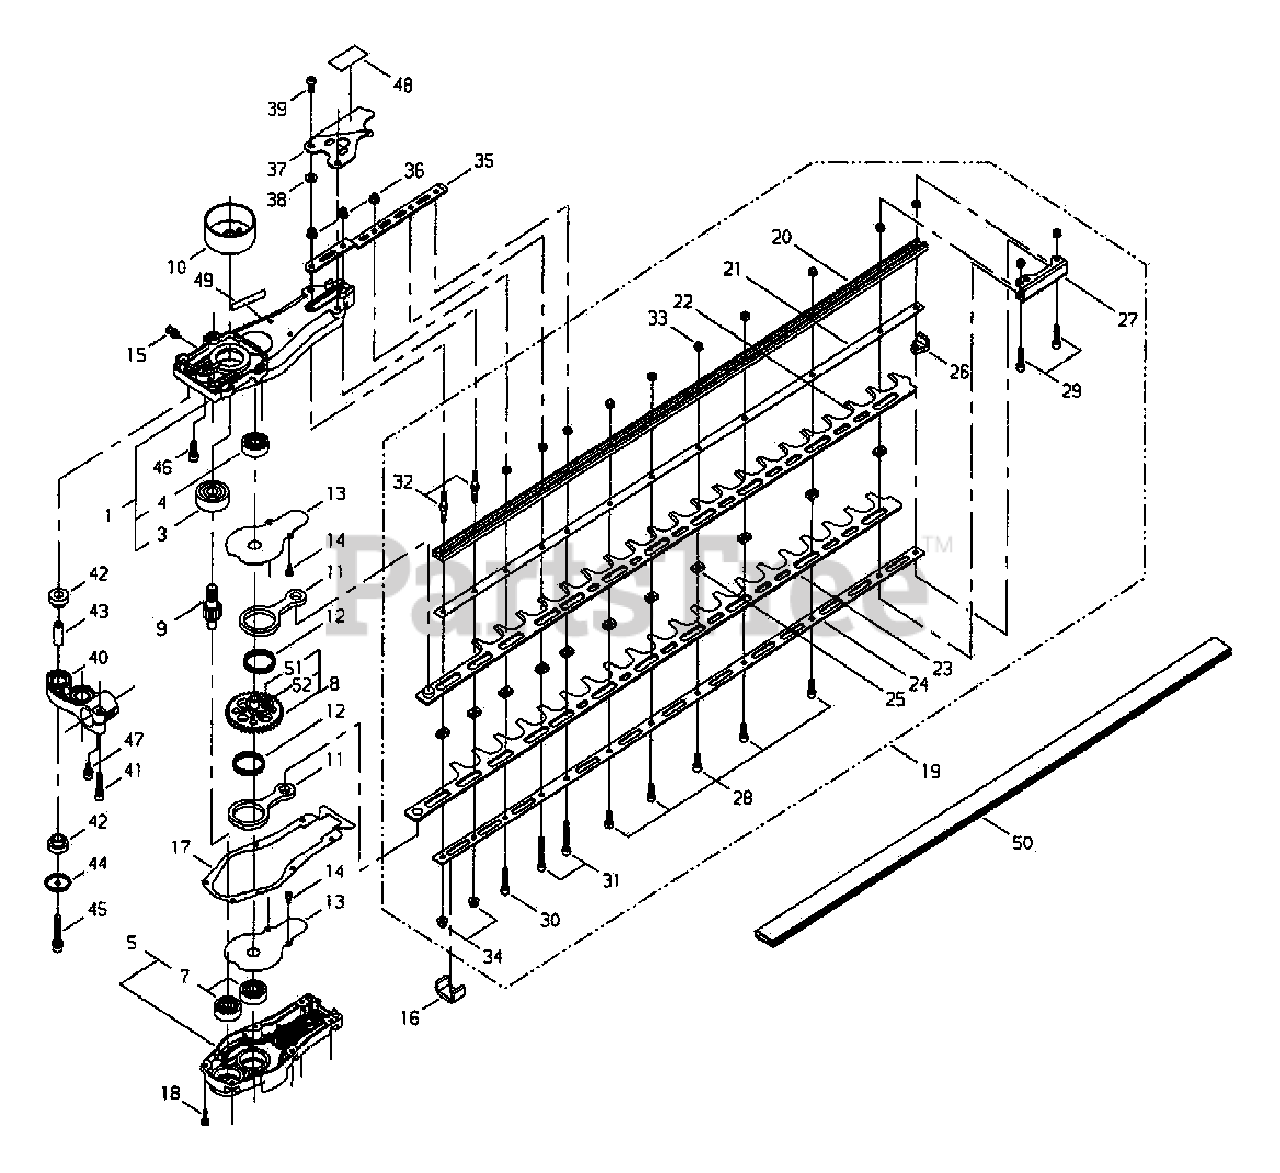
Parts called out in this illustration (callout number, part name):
1	GEAR CASE ASSY
3	BEARING, BALL - 6301DDU
4	BEARING, BALL - 6200ZZ
5	GEAR CASE COVER ASSY
7	BEARING, BALL - 6200ZZ
8	CAM GEAR ASSY
9	GEAR - PINION
10	DRUM, CLUTCH
11	ROD, CONNECTING
12	BEARING, NEEDLE - 30
13	PLATE, GEAR CASE
14	SCREW - 4X8
15	FITTING, GREASE
16	SEAL, FELT
17	GASKET, GEAR CASE
18	SCREW - 4X14
19	BLADE KIT - 30" (76cm)
20	SUPPORT, BLADE - 30" (76cm)
21	PLATE - UPPER
22	BLADE - 30" (76mm) -- UPPER
23	BLADE - 40" (101cm) HD -- LOWER
24	PLATE - LOWER
25	SPACER
26	BLOCK
27	PLATE, GUIDE
28	SCREW - 5X14
29	SCREW - 5X20
30	SCREW - 5X25
31	STUD - 5
32	SCREW - 5X35
33	LOCKNUT - 5
34	NUT - 5
35	PLATE, ANGLE
36	NUT - 5
37	PROTECTOR
38	WASHER - 5
39	SCREW - 6X12
40	MOUNT, HANDLE
41	SCREW - 5X25
42	CUSHION
43	COLLAR - 6
44	COVER, CUSHION
45	SCREW - 6X35
46	SCREW - 6X16
47	SCREW - 5X12
48	LABEL - WARNING
49	LABEL - LUBRICATION
50	COVER, BLADE - 30" (76cm)
51	GEAR - SPUR
52	CAM
